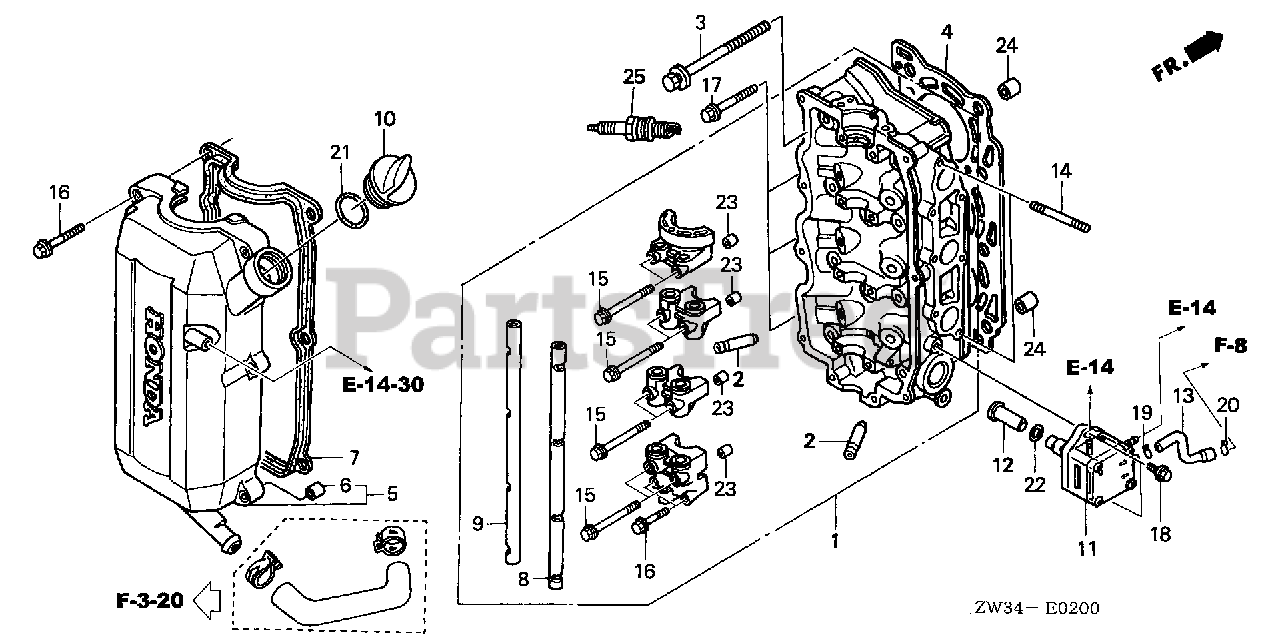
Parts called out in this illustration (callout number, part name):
1	CYLINDER HEAD ASSY. *NH8* (DARK GRAY)
2	GUIDE, VALVE (OVER SIZE) (EXHAUST SIDE)
3	BOLT-WASHER (10X85)
4	GASKET, CYLINDER HEAD
5	COVER, CYLINDER HEAD
6	COLLAR, HEAD COVER
7	GASKET, HEAD COVER
8	SHAFT, IN. ROCKER ARM
9	SHAFT, EX. ROCKER ARM
10	CAP, OIL
11	PUMP ASSY., FUEL
12	LIFTER, FUEL PUMP
13	TUBE B, FUEL
14	BOLT, STUD (6X28)
15	BOLT, FLANGE (6X70)
16	BOLT, FLANGE (6X35)
17	BOLT, FLANGE (8X40)
18	BOLT, FLANGE (6X20) (SH)
19	CLIP, TUBE (B10)
20	CLIP, TUBE (B12)
21	O-RING (26X2.7)
22	O-RING (20.8X2.4)
23	PIN A, DOWEL (8X14)
24	PIN A, DOWEL (12X16)
24	PIN, DOWEL (6X10)
25	SPARK PLUG (DR7EA) (NGK)
25	SPARK PLUG (X22ESR-U) (DENSO)
